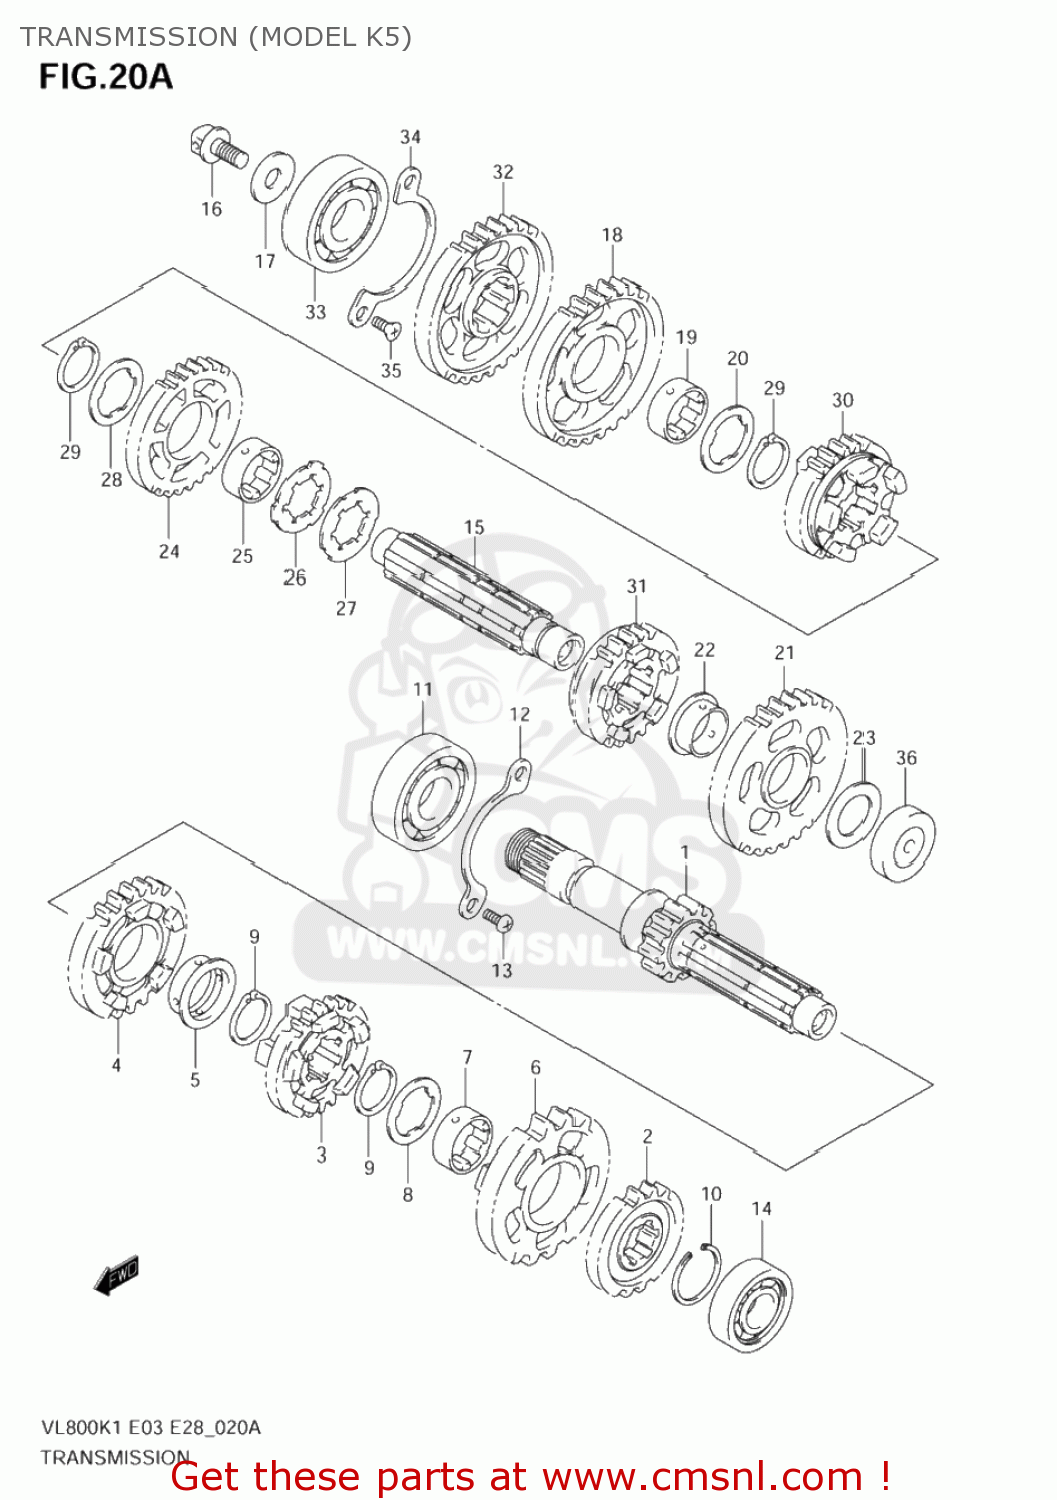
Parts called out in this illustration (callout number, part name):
1	SHAFT,COUNTER
2	GEAR,2ND DRIVE(NT:19)
3	GEAR,3RD DRIVE(NT:22)
4	GEAR,4TH DRIVE(NT:25)
5	BUSH
6	GEAR,5TH DRIVE(NT:27)
7	BUSH,6TH DRIVE GEAR
8	WASHER,LOCK
9	RING,SNAP
10	CIRCLIP
11	BEARING(25X62X17)
12	RETAINER,CNTR SHAFT BEARING
13	SCREW(6X12)
14	BEARING(20X47X14)
15	SHAFT,DRIVE
16	NOZZLE,DRIVE SHAFT
17	WASHER
18	GEAR,1ST DRIVEN(NT:32)
19	BUSH
20	WASHER,LOCK
21	GEAR,2ND DRIVEN(NT:31)
22	BUSH
23	SHIM(20X34X1)
24	GEAR,3RD DRIVEN(NT:27)
25	BUSH
26	WASHER
27	WASHER,LOCK
28	WASHER,LOCK
29	CIRCLIP
30	GEAR,4TH DRIVEN(NT:25)
31	GEAR,5TH DRIVEN(NT:22)
32	GEAR,REDUCTION DRIVE(NT:30)
33	BEARING(20X52X15)
34	RETAINER,DRIVE SHAFT BEARING
35	SCREW(6X12)
36	BEARING(20X52X15)
